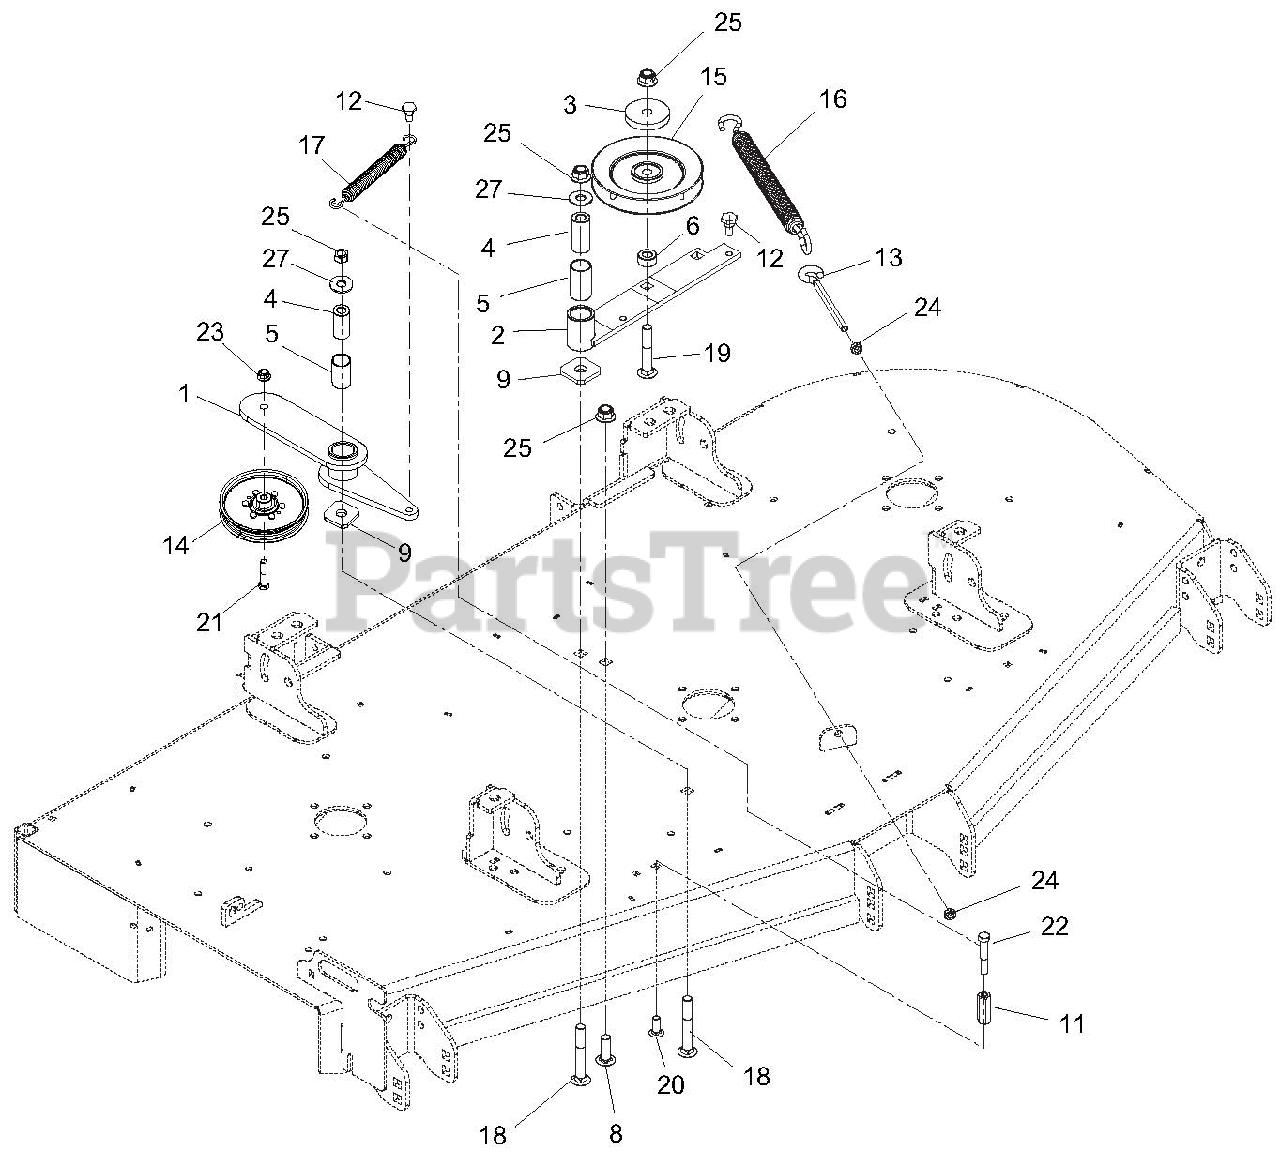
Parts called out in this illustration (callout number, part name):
1	WMT, IDLER ARM
2	WMT, IDLER PIVOT ARM
3	CAP, IDLER BEARING SEALING
4	BSHG, SPCR .502X.997X2.03
5	BSHG, 1.00X1.125X1.937
6	BSHG, SPCR .502 X .997.50 PM
8	BLT, RNHDSQSHNK 1/2-13 X 2.00 FULL
9	WSHR, -FLT.640X1.75X.250
11	NUT-HEX COUPLING
12	BLT, SHLDR EP .38-16X.30 HEX
13	BOLT, .38-16X6.00 .62 DIA EYE
14	SHV, .38" ID X 5.0’’ OD V-IDLER
15	SHEAVE, .50" ID X 6.00" OD V-IDLER
16	SPRG, EXTENSION
17	SPRG, EXT. .845 X 6.55
18	BLT-RDHDSQNK .50-13X3.50YG5
19	BLT-RDHDSQNK .50-13X3.00YG5
20	BLT-RDHDSHSQNK.38-16X1.0 G5YZ
21	BLT-HEX .38-16X2.00 GR5 YWZC
22	BLT-HEX .38-16X1.75 GR5 YWZC
23	NUT-LK-NYL-FLG .38-16 YWZC
24	NUT, 3/8-16 JAM GR5
25	NUT-LK-NYL-FLG .50-13 YWZC
27	WSHR-FL-STL.563X1.38X.109YWZC
